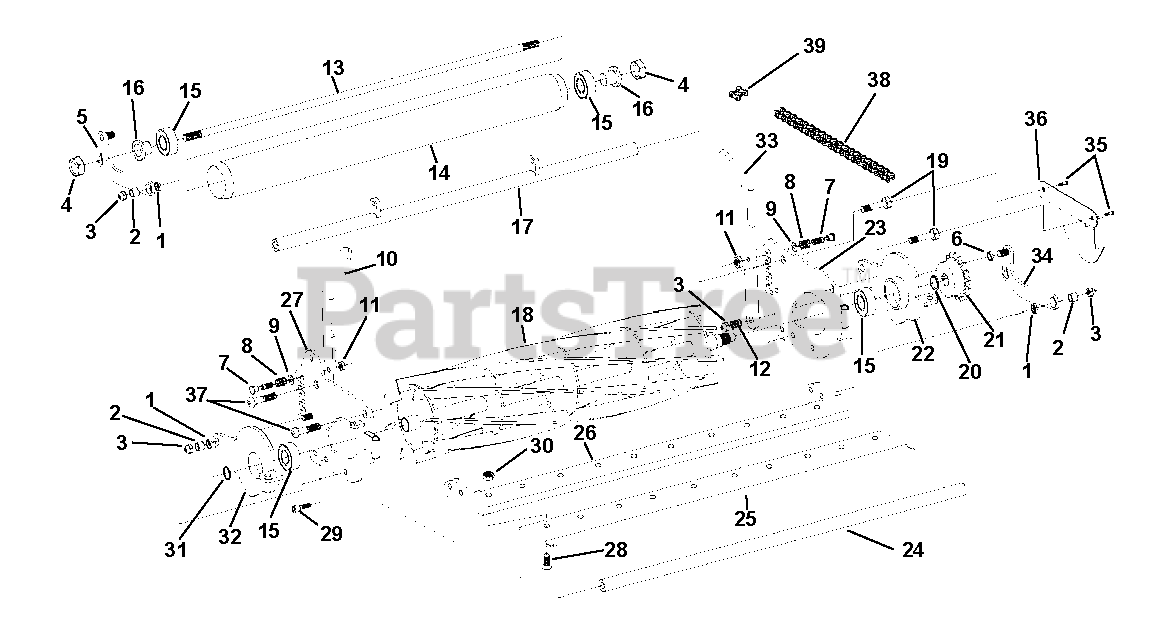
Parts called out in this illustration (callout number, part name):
3	Nut, .375-24 Nyloc Jam
4	Nut, Jam Nyloc .50-20
5	Arm, Rear Roller Height Right Hand
6	Bushing, 60 Degree
7	Pin, Quick Adjust
8	Spring, Quick Adjust
9	Washer, Quick Adjust
10	Handle, Quick Adjust Right Hand
11	Nut, Hex .312-24
13	Axle, Roller 25-Inch (995310)
14	Tube, Roller 25-Inch (995310)
15	Bearing 47 mm x 20 mm x 14 mm
17	Bar, Rear Spacer 25-Inch (995310)
18	Reel, 25-Inch 6-Blade (995310)
19	Cap Screw, Special, Hex Head .50-13 x 1.25
21	Sprocket, 17 Tooth
22	Housing, Bearing Left Hand
23	Side Plate, Left Hand
24	Bar, Spacer 25-Inch (995310)
25	Bed Knife 25-Inch (995310)
26	Weldment, Bedbar 25-Inch (995310)
27	Side Plate Right Hand
28	Screw, Hex Socket Flat CSK Head .312 x 1
29	Cap Screw, Hex Socket Head .38-16 x .625 Stainless Steel
30	Nut, Hex Nyloc .312-18
31	Snap Ring, .75 External
32	Housing, Bearing Right Hand
33	Handle, Quick Adjust Left Hand
34	Arm, Rear Roller Height Left Hand
35	Screw, Pan Head Slotted, Stainless Steel .25-28
36	Chain Guard, Reel
37	Screw, Button Head .50-13 x 1
38	Chain, Reel Drive (56" # 423)
39	Master Link
